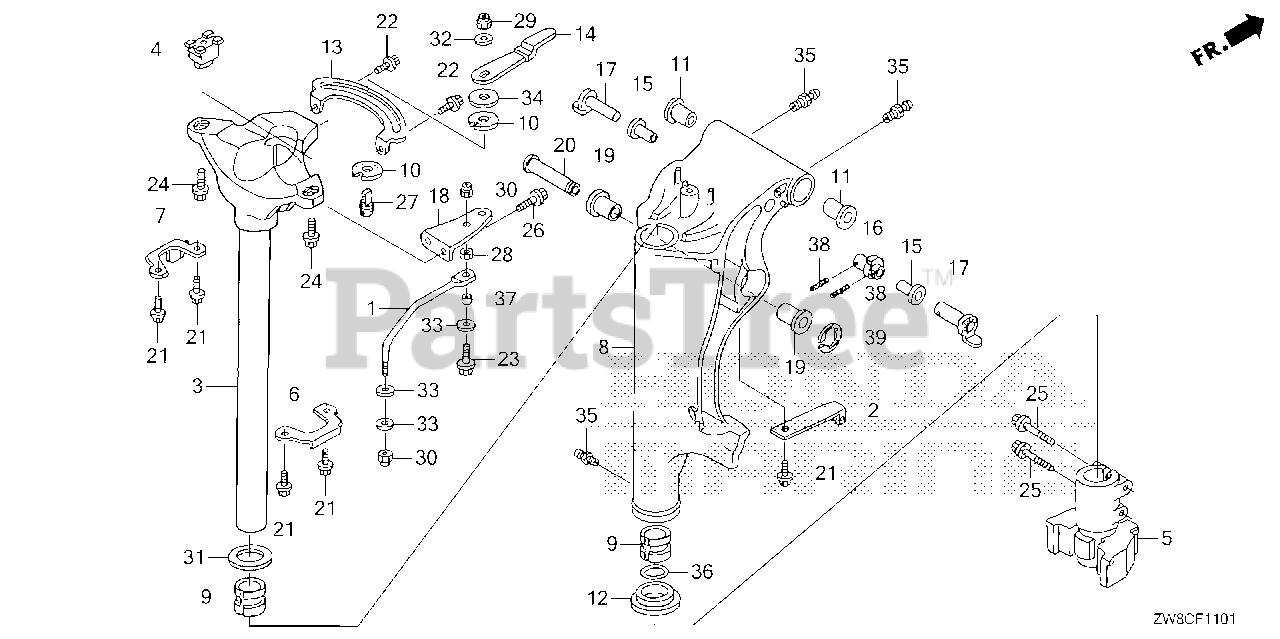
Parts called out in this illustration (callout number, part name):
2	SPRING, CLICK
3	FRAME, MOUNTING (L)
4	RUBBER, MOUNTING (UPPER)
5	RUBBER, MOUNTING (LOWER)
6	COVER, MOUNTING RUBBER (UPPER)
7	COVER, MOUNTING RUBBER (UPPER) (PT)
8	CASE, SWIVEL *NHB14M* (L)(PT) (AQUA MARINE SILVER METALLIC)
9	LINER, SWIVEL CASE
10	BLOCK, FRICTION
11	BUSH, SWIVEL CASE
12	COLLAR, SWIVEL CASE
13	PLATE, FRICTION
14	LEVER, FRICTION
15	BUSH, TILT ARM
16	BRACKET, TILTING
17	STOPPER, TILT
19	BUSH, CYLINDER (LOWER)
20	PIN, CYLINDER (UPPER)
21	BOLT, FLANGE (6X12)
22	BOLT, FLANGE (6X12)
24	BOLT, FLANGE (10X25)
25	BOLT, FLANGE (8X45)
27	BOLT, STUD (8X26)
29	NUT, SELF-LOCK (8MM)
31	WASHER, THRUST
32	WASHER (8MM)
34	WASHER, NYLON (8MM)
35	NIPPLE, GREASE
36	O-RING (34X2.4)
38	PIN, SPRING (2.5X20)
39	E-RING (15MM)
